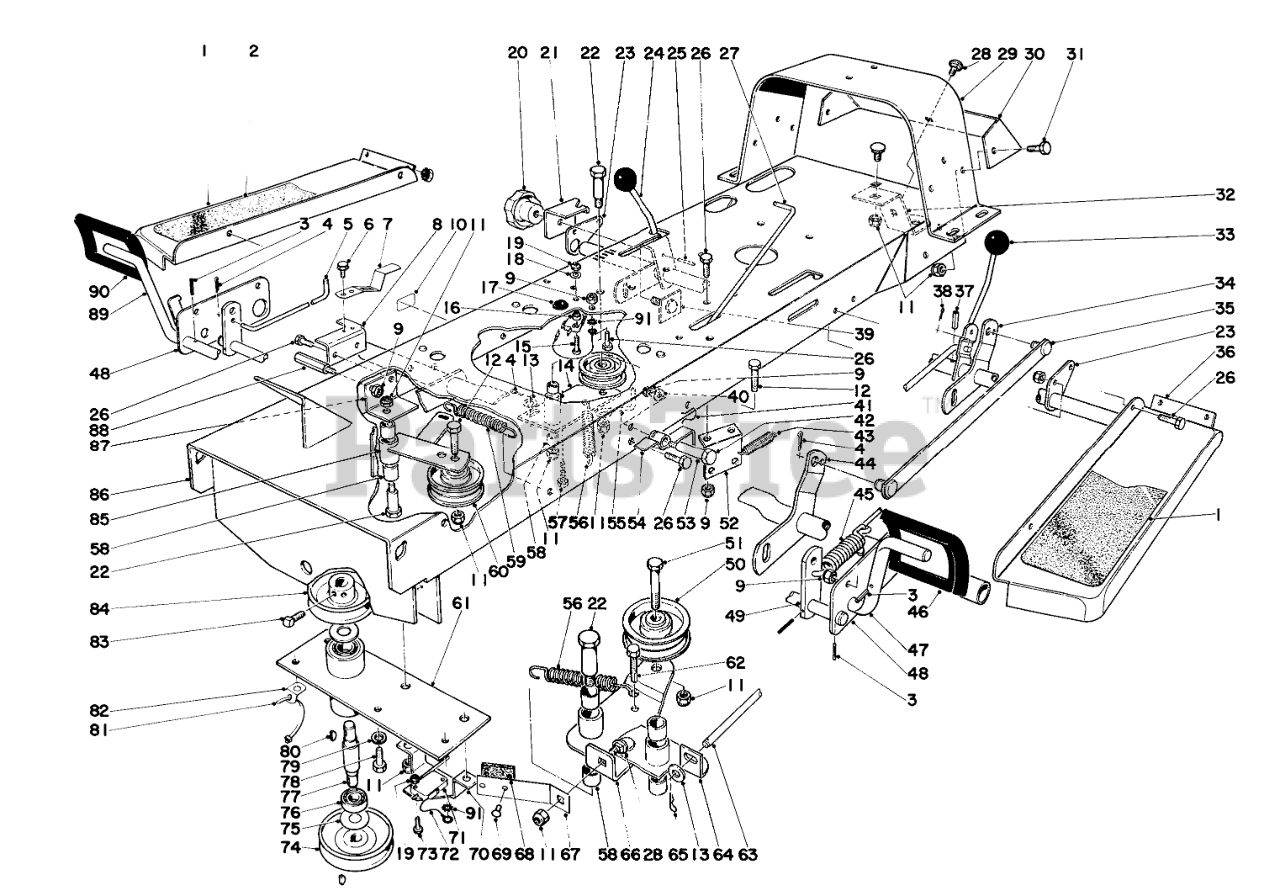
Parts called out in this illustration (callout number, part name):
1	Footrest
2	Foot Pad
3	PIN-SPRING
4	PIN-COTTER
5	Clutch Rod
7	Brake Lock
8	Bracket-Brake Lock
9	NUT-LOCK, CONE
10	Decal Brake
11	NUT-LOCK, CONE
12	SCREW-HH
13	WASHER-FLAT
14	Idler Arm (Incl. Ref. #58)
15	SCREW-PPH
16	Spacer
17	GROMMET
18	WASHER
19	NUT-LOCK, NI
21	Slide Height Adj.
22	Axle Bolt
23	Bracket Tube
24	Rod Control Hgt. Adj.
25	PIN-SPRING
26	SCREW-HH
27	Brake Rod
28	SCREW-CARR
29	Rear Support
30	Frame Member Rear
31	SCREW-HH
32	Bracket Hitch
33	KNOB-CONTROL
34	Rear Height Adj. Tube
35	Height Adj. Link
36	Footrest
37	1/8 X 1-3/8 ROLL PIN
38	PIN-COTTER
39	Knob Plate
40	WASHER-PLAIN
41	Retainer Clutch Lock
42	SCREW-HH
43	Spring
44	Front Height Adj. Tube
45	Spring Brake Rod
46	CLUTCH PAD
47	Clutch Pedal
48	Plate Tube
49	Arm Lever
50	PULLEY-IDLER
51	SCREW-HH
52	Belt Guide
53	Spacer
54	Clutch Lock
55	Belt Retainer
56	Spring
57	Sems Screw
58	BUSHING
59	Spring-Idler Tension
60	PULLEY-IDLER
61	Pulley Tube
62	Sems Screw
63	Clutch Rod Blade
64	Pivot Bracket (Incl. Ref. #58)
65	PIN-COTTER
66	Idler Plate (Incl. Ref. #58)
67	Clutch Brake
68	BLADE BRAKE LINING
69	Rivet
70	Bracket Switch
71	MICRO SWITCH
72	Wire Assembly
73	SCREW-HEAD, PAN
74	Pulley
75	Bearing Washer
76	Bearing
77	Pulley Shaft
78	SCREW-HH
79	WASHER-LOCK
80	KEY-WOODRUFF
81	Cable Tie
82	Strap Cable Tie
83	5/16-18 X 1/2 SQ HD
84	Pulley
85	Idler Plate (Incl. Ref. #58)
86	Frame
87	Mount Idler Pulley
88	Pedal Stop
89	Brake Pedal
90	PAD-BRAKE
91	WASHER-LOCK
